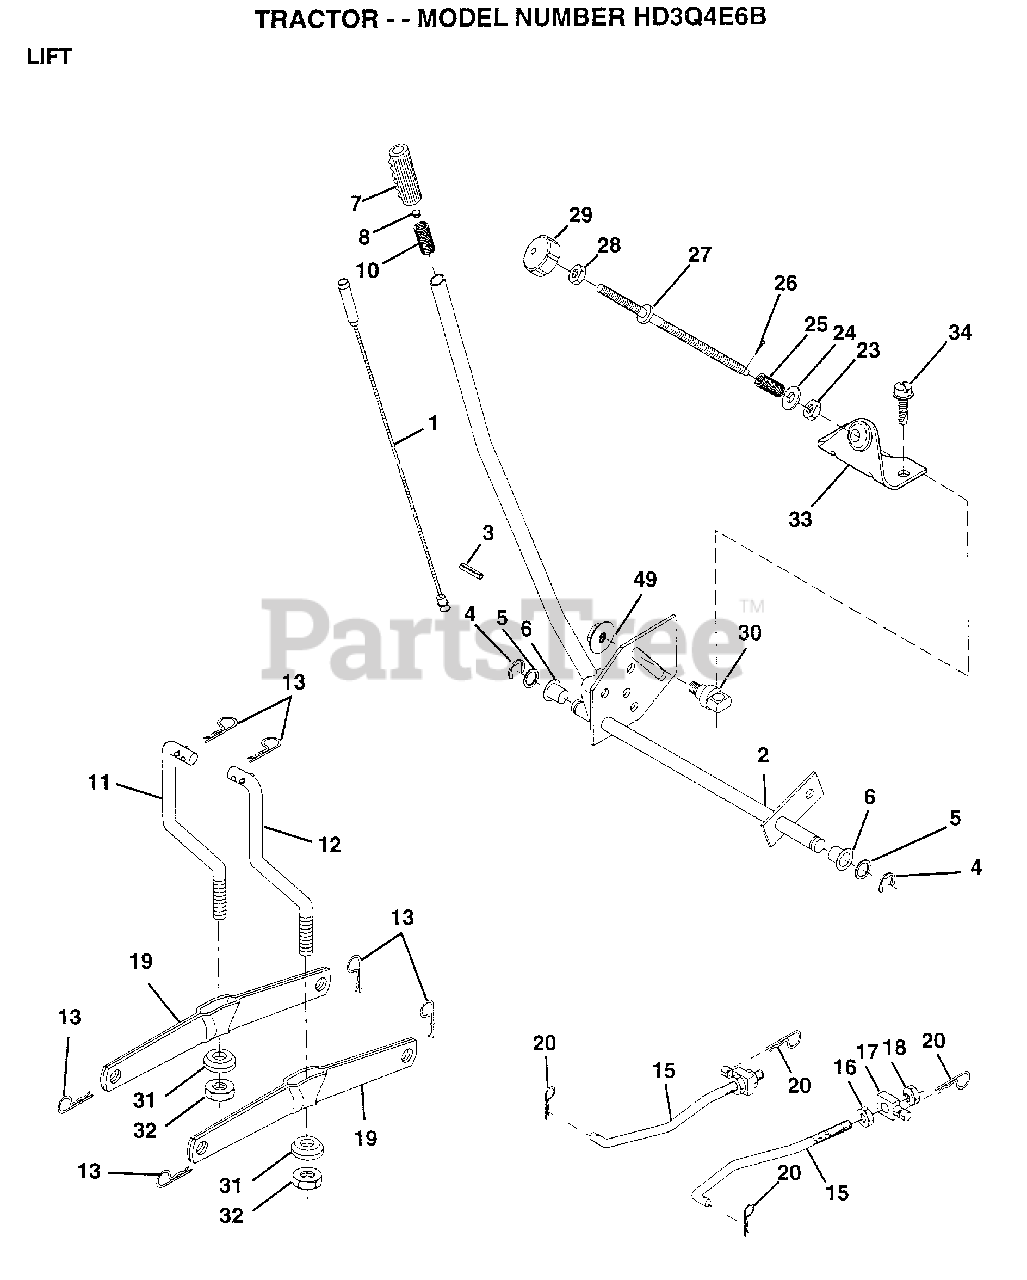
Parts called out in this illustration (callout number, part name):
1	WIRE ASM
2	HANDLE.LIFT.LH.
3	PIN GROOVE
5	WASHER
6	NYLON BEARING
7	GRIP HANDLE
15	LINK.FRONT
16	NUT
17	TRUNION
18	NUT.LK.W/WSH.1/2.
19	ARM SUSP REAR
20	RETAINER.SPRING
23	NUT T
24	WASHER
25	SPRING T
28	NUT
29	KNOB INF 3/8-16
30	TRUNNION
31	BEARING PVT LH
32	NUT.CROWNLOCK.3/8
33	BRACKET STOP INF
34	SCREW LT
49	NUT.HXFLG.LOCK.
